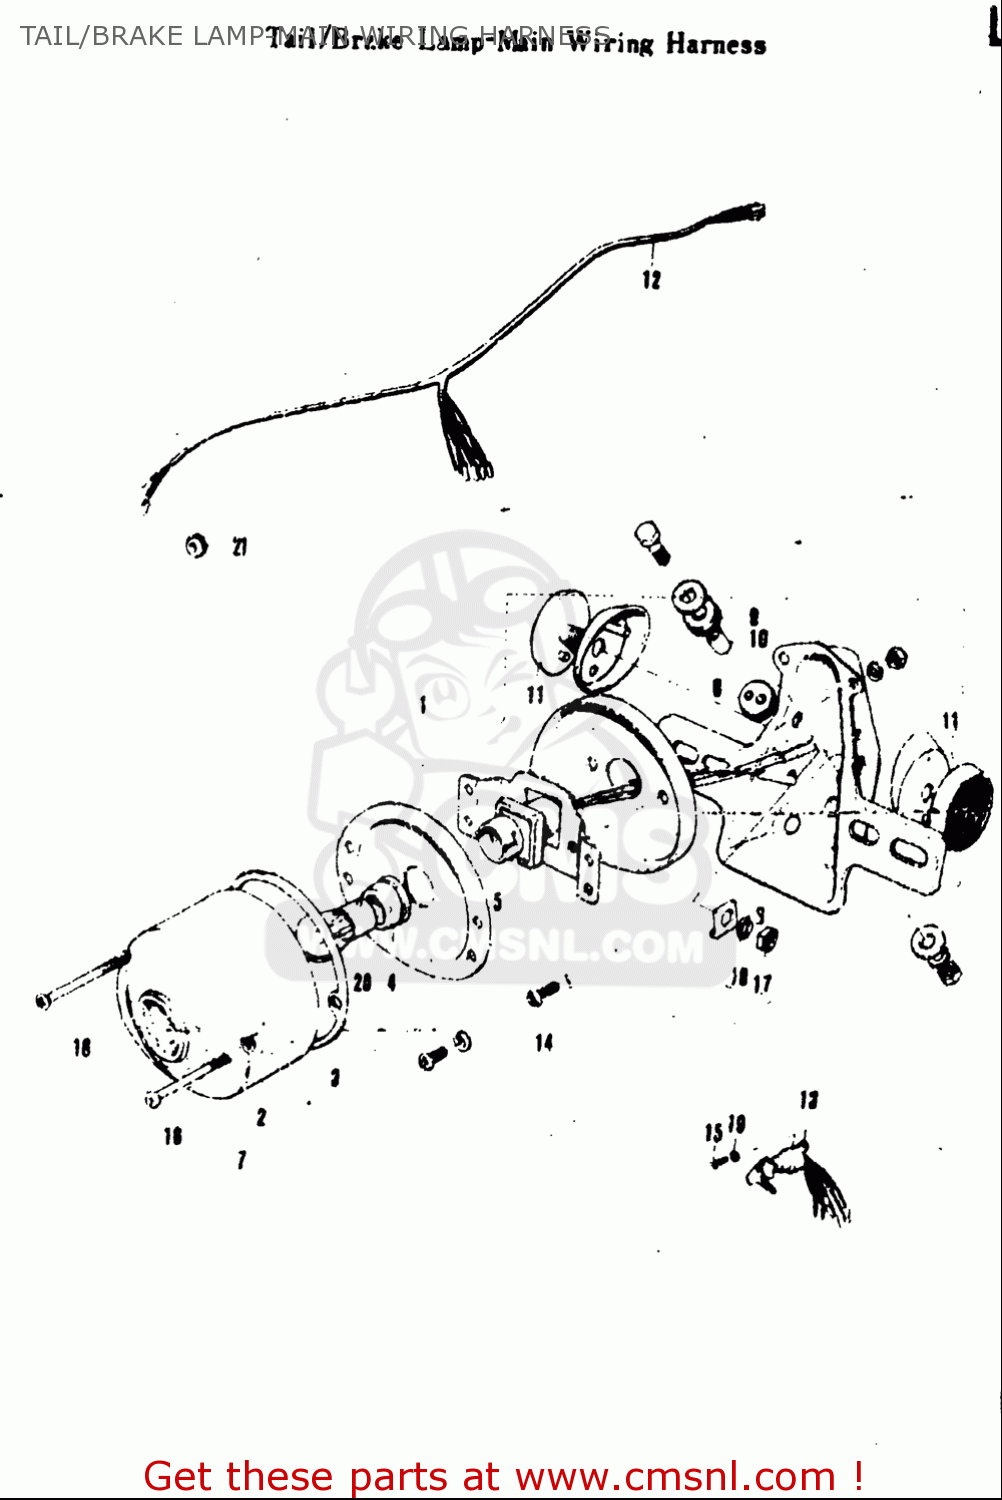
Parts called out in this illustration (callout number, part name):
2	LENS,RR COMBINATION LAMP
8	GROMMET,REAR COMBINATION LAMP
9	CUSHION
10	SPACER
17	NUT
18	WASHER,LOCK
19	WASHER,LOCK
20	BULB(6V17/5.3W,STANLEY,A4813)
